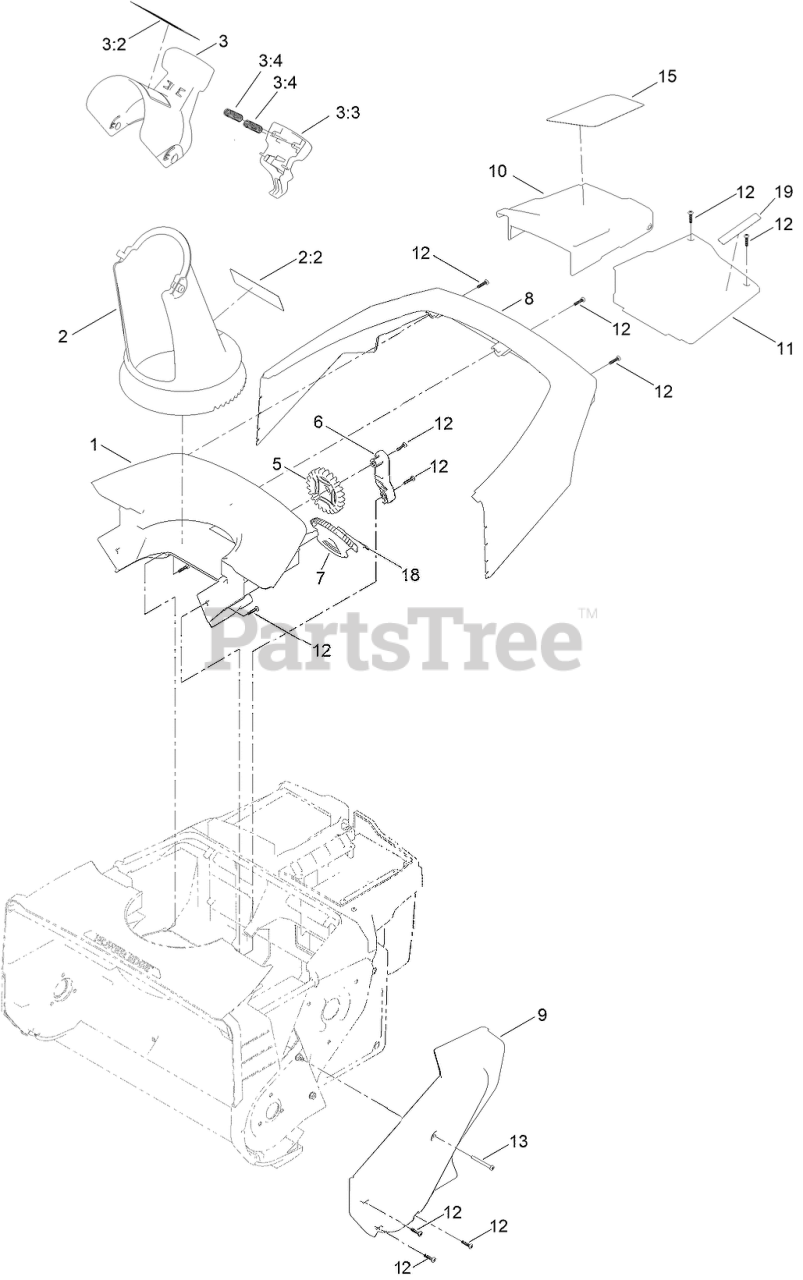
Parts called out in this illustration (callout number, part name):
1	CHUTE-REAR
2:2	DECAL-DANGER, DISCHARGE
3	DEFLECTOR-CHUTE
3:2	DECAL-DANGER
3:3	TRIGGER-DEFLECTOR
3:4	SPRING-COMPRESSION
5	GEAR-CHUTE
6	BRACKET-GEAR
7	GEAR-SECTOR
8	SHROUD
9	COVER-BELT
10	COVER-BATTERY
11	COVER-CONTROLLER
12	SCREW-PPH
13	SCREW-PLASTIC, PPH
15	DECAL-BATTERY, 60V SNOW
18	CLIP-HANDLE
19	DECAL-BRUSHLESS
